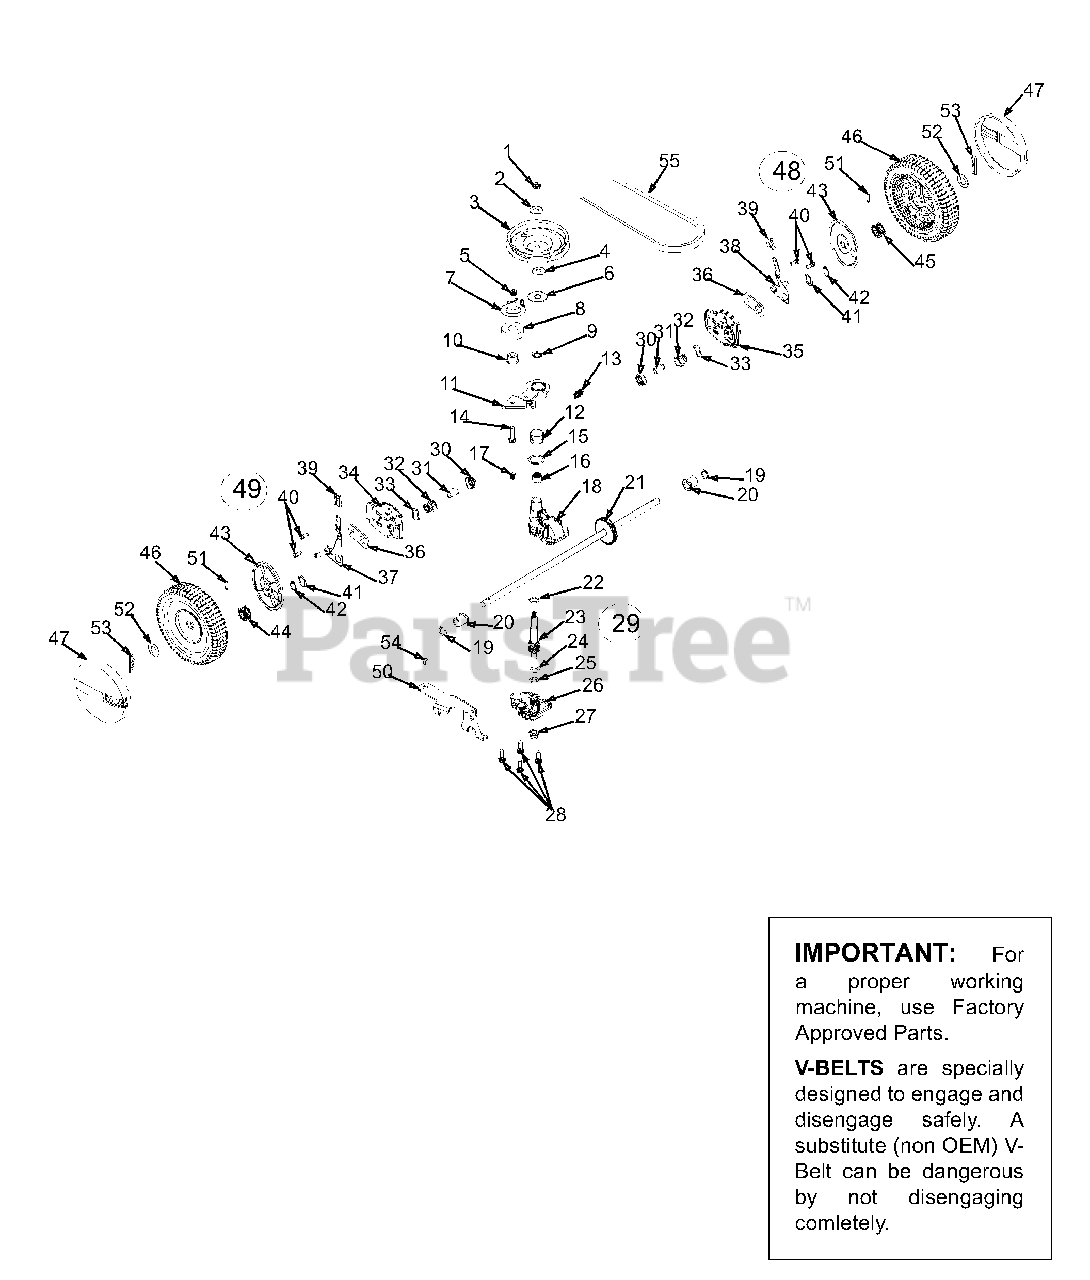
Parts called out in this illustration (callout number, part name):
1	Hex Jam Nut 5/16-24
2	Bell Wash .325 x .930 x .045
3	Pulley
4	Bell Wash .325 x .930 x .045
5	Hex Nut 1/4 - 28 Lock
6	Flat Wash .442 x 1.38 x .060
7	Belt Keeper
8	Ball Bearing
9	Oil Seal
10	Flange Spacer
11	Idler Bracket Ass'Y
12	Bearing Sleeve
13	Wash:Flat:.504 x .700 x .030
14	Hex Cap Screw 1/4-28 x 1.00 Gr. 5
15	Flat Washer .865 x 1.145 x .030
16	Needle Bearing .438 x .625 x .500
17	Plug 1/4 x .437
18	Housing Asm:Upper:
19	Seal:Oil:.500x .687 x .094
20	Flange Bearing .503 x .689 x .792
21	Output Shaft
22	Flat Washer .504 x .700 x .030
23	Pinion Shaft 10T.
24	Thrust Washer .375 x .70 x .030
25	Thrust Washer .388 x .625 x .062
26	Housing:Lwr:
27	Flange Bearing .378 x .531 x .370
28	Hex Screw w/Wash 1/4-20 x .750
29	Transmission-Complete
30	Bearing Retainer
31	Bearing Sleeve .50 I.D.
32	Bearing Support
33	Wave Washer 1.5 x 1.0 x .029
37	Front Lever R.H
38	Front Lever L.H.
39	Knob
40	Hex Cap Screw 3/8-16 x .75
41	Washer DD 1.5" O.D.
42	Snap Ring 1.0 Dia
43	Wheel Dust Cap
44	Gear 14T RH Fwd
45	Gear 14T LH Fwd
46	Whl 8x1.75 Disk Bar Gray Sleev S
47	Hubcap:Euro:Grey
48	Height Adj. Complete RH
49	Height Adj. Complete LH
50	Cable Idler Bracket
51	Dowel Pin
52	Flat Washer 1/2 x 1.00 x .063
53	Cotter Pin .08 x 1.42
54	Scr.Sh Ldr. .375 x .25AB: 1/4-20 Thd.
55	"V"-Belt
